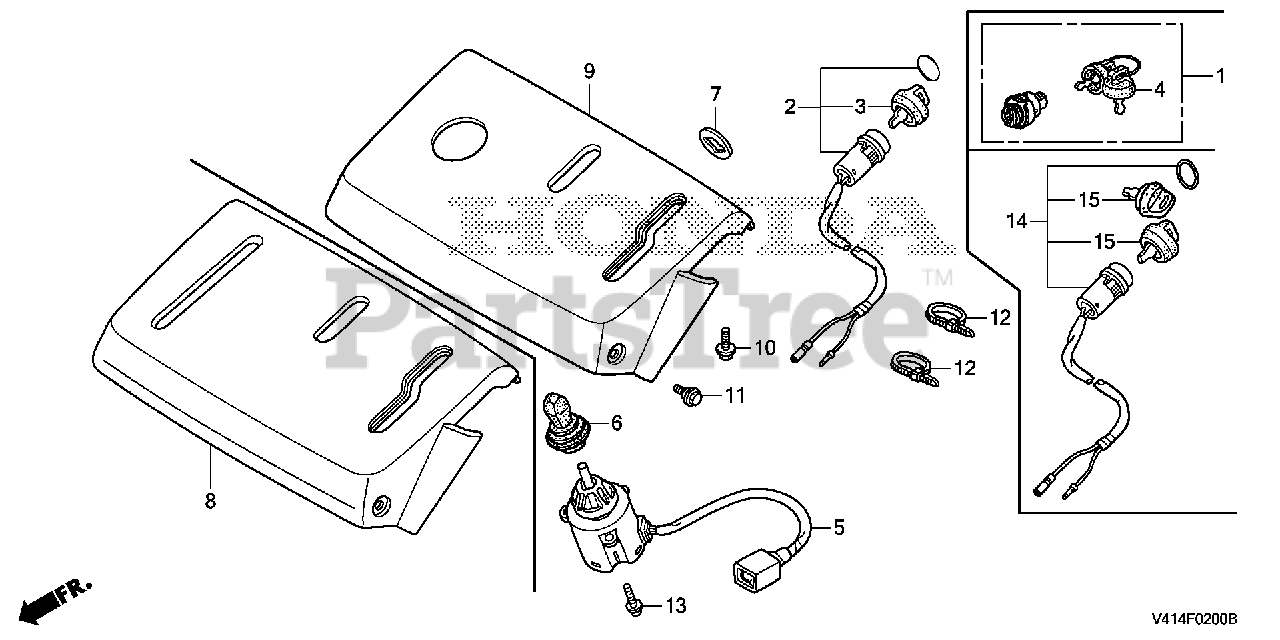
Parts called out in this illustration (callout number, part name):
2	SWITCH ASSY., COMBINATION
3	KEY ASSY., COMBINATION SWITCH (RED)
7	SPACER, ENGINE STOP SWITCH
8	PANEL, CONTROL *NH296* (ALPS GRAY)
10	BOLT, FLANGE (5X12)
11	BOLT, CONTROL PANEL
12	BAND, WIRE (95MM)
